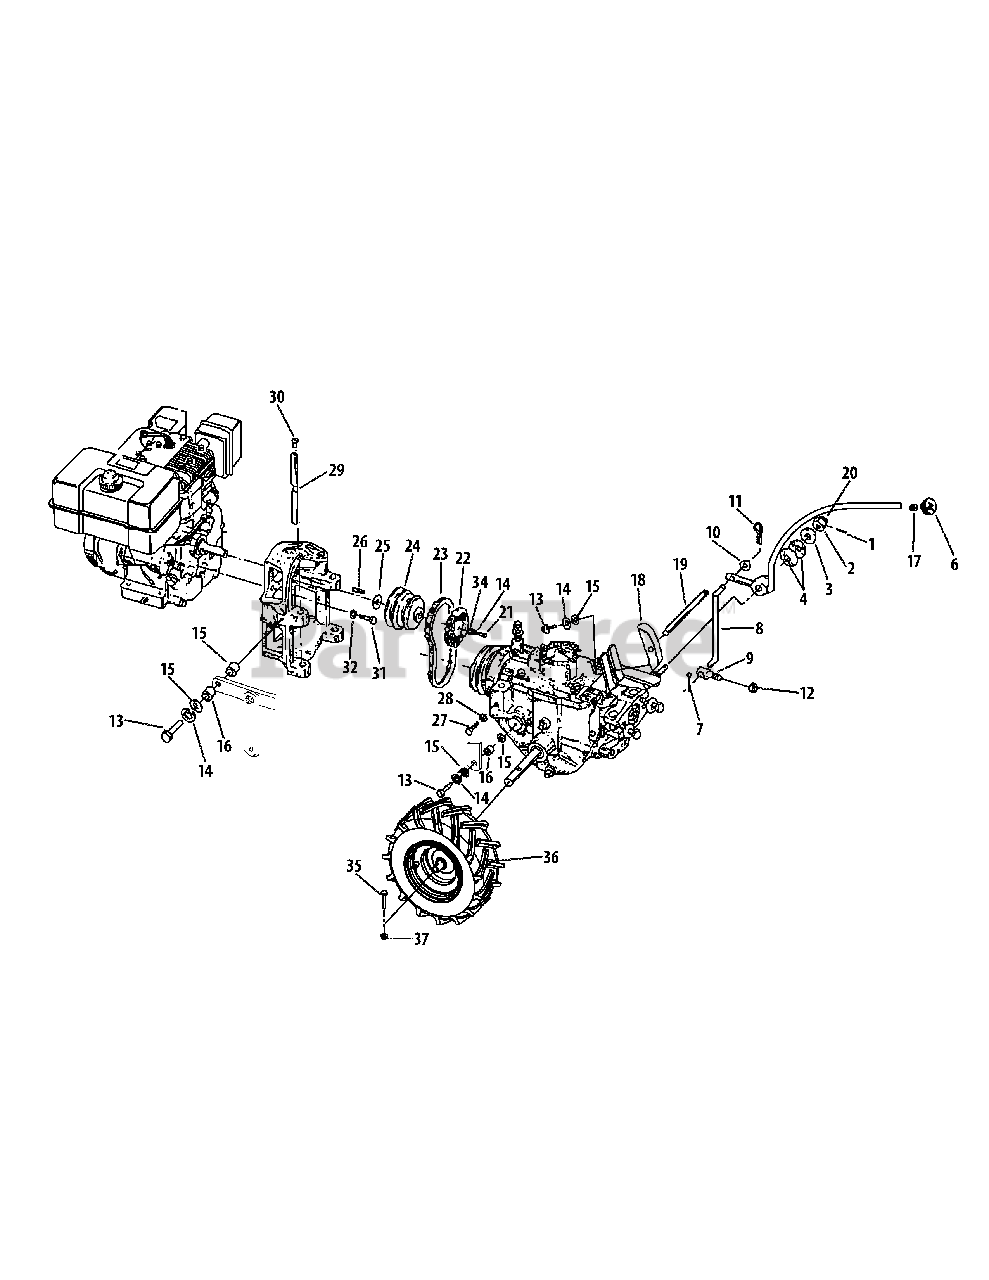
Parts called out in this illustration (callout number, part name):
1	Spring Pin, 1/8"
2	Flat Washer, .510 x 1.0 x .125
3	Shoulder Washer, 1/2"
4	Disc Spring Washer
5	Wheel Speed Shift Lever
7	Cotter Pin, 3/32" x 1"
8	Connecting rod
10	Flat Washer, 5/16"
11	Hair Pin Cotter
12	Hex Locknut, 5/16"-18
13	Hex Bolt, 3/8 -16 x 1"
14	Spring Lockwasher, 3/8 "
15	Flat Washer, 3/8 "
16	Spacer Bushing, 19/64"
17	Retaining Ring
18	Belt Adjustment, 3- 7/8"
19	Belt Adjustment Rod
20	Hex Nut, 1/2-20
21	Hex Bolt, 3/8 -24 x 1.75
22	Reverse Disc
23	Forward Drive Belt
24	Engine Power Take-off Pulley
25	Flat Washer, .766 x 1.0 x .031
26	Engine Pulley Key, 3/16"x 2-1/2"
27	Hex Bolt, 5/16-18 x 1"
28	Hex Nut, 5/16-18
29	Engine Mounting Bar
30	Thread Protector Plug
31	Hex Bolt, 5/16-24 x 1-1/8 "
32	Spring Lockwasher, 5/16"
34	Flat Washer, .406 x 1.0 x .105
35	Hex Screw, 1/4-20 x 1-1/2"
36	Wheel Assembly, 16 x 4.6 x 8"
37	Hex Flange Nut, 1/4-20
